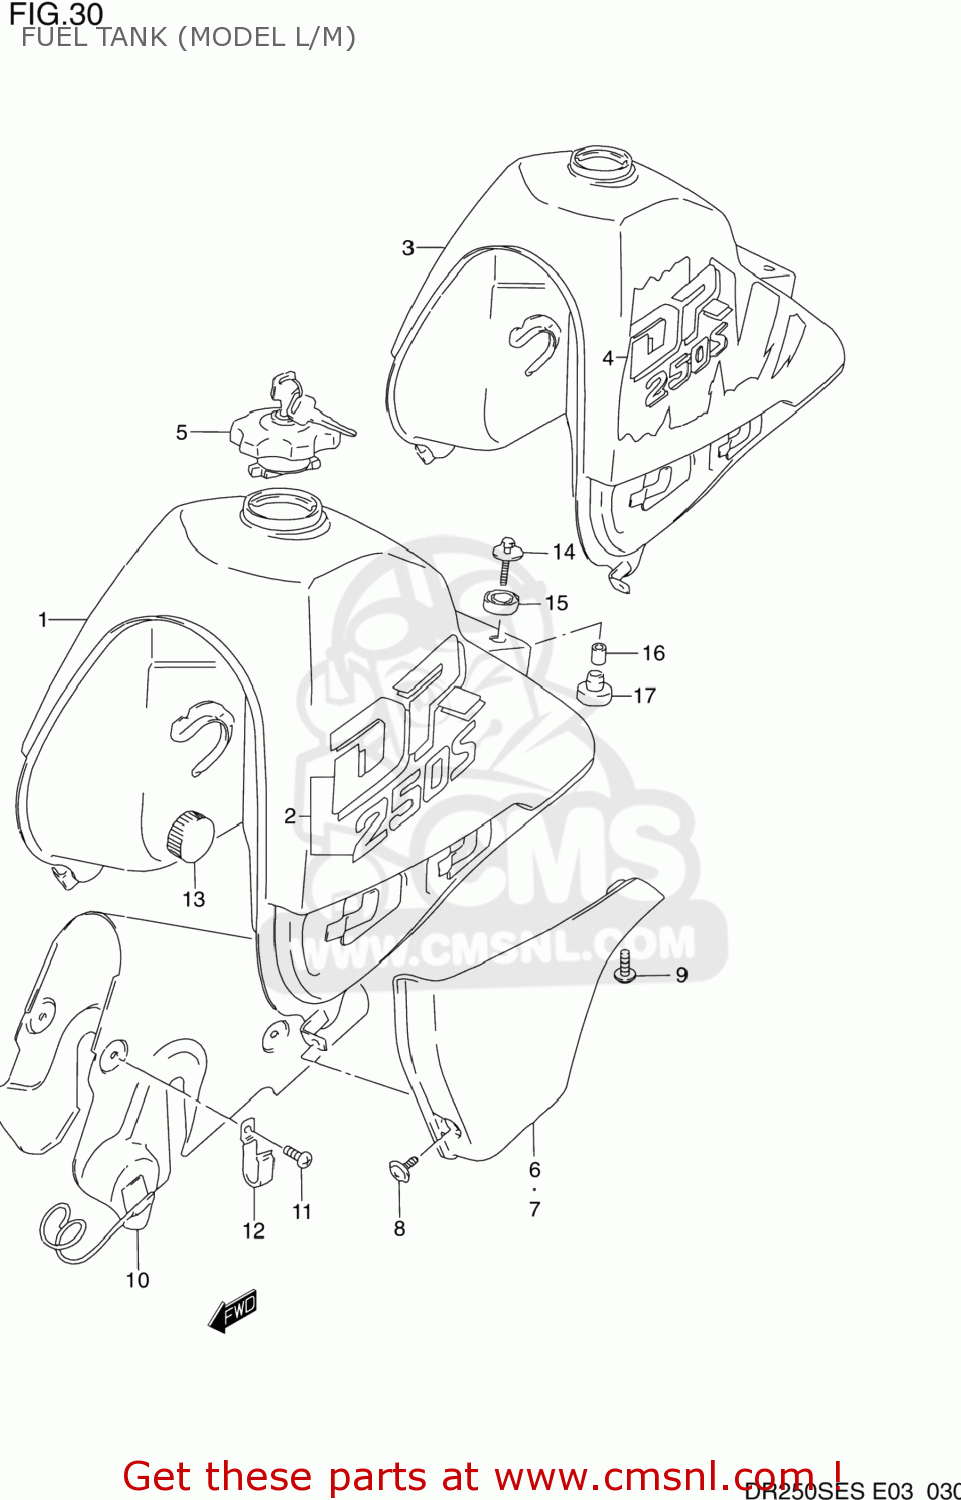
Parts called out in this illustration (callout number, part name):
1	TANK ASSEMBLY,FUEL
2	EMBLEM,FUEL TANK
3	TANK ASSEMBLY,FUEL
4	TAPE SET, FUEL TANK
5	CAP SET,FUEL TANK
6	COVER,FUEL TANK,R
7	COVER,FUEL TANK,L
8	SCREW
9	SCREW(6X12)
10	SHIELD,FUEL TANK
11	SCREW
12	CLAMP
13	CUSHION
14	BOLT
15	CUSHION
16	SPACER
17	CUSHION
